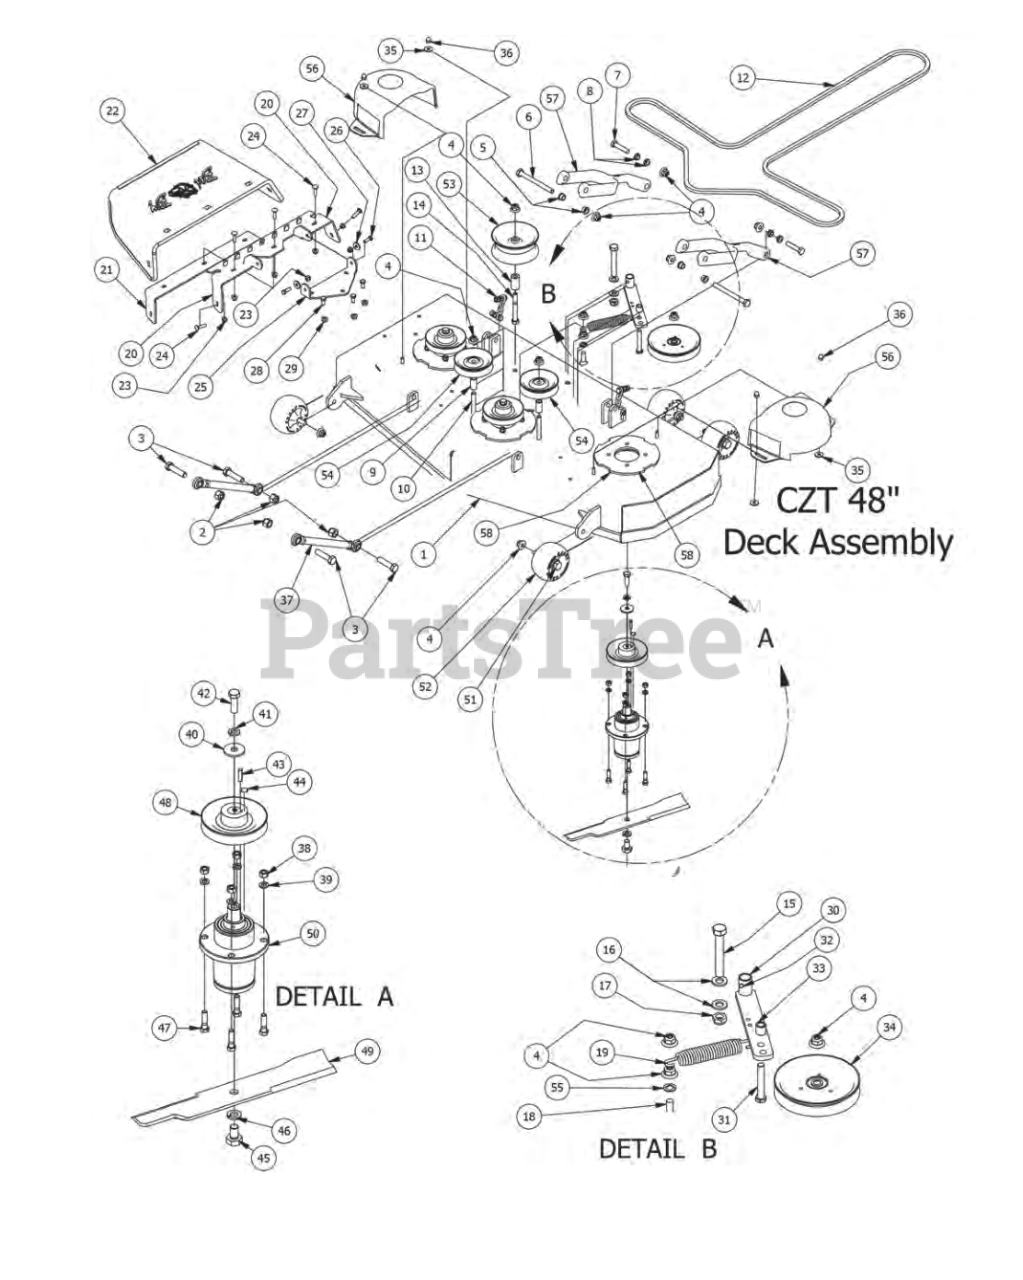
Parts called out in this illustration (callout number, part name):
1	2014 ZT/CZT 48" Deck
2	5/8 Std NC Nylock Nut
3	5/8" x 2 1/2" Gr5 Hex Bolt (Coarse)
4	1/2-13 Nylon Flange Nut-Orange
5	Flange Bushing For Deck Arm upper
6	1/2" x 5 1/2" Bolt
7	1/2-13X 2-1/4 GR Hex Bolts
8	Flange for Lower Deck Arm
9	502 ID X.75 OD X 1.500 Leng
10	1/2 x 3 1/2 Flange Bolt Grade 8
11	2015 CZT Deck Hanger Chain
12	50" Deck Belt
13	1 3/4" Pulley Spacer
14	1/2" x 4" Bolt (Grade 8)
15	5/8" x 4" Hex Bolt
16	635 ID Plastic Washer
17	5/8-11 Nylon Insert Jam Half Nut
18	1/2 x 1-1/2 Carriage Bolt
19	2009 Deck/Pump Idler Spring
20	Upper Hanger
21	Discharge Lower Chute Bracket
22	Rubber Discharge Chute
23	5/16" Nylon Flange Nut
24	5/16" x 1 1/4" Carriage Bolt
25	Discharge Chute Hanger (deck mounted)
26	5/16" x 1" Bolt
27	360 ID Plastic Washer
28	3/8" x 3/4" Hex Bolt
29	3/8" Flange Nut
30	Deck Idler
31	1/2-13 x GR 5 Hex Bolt Zinc
32	1/4" Press in Grease Fitting
33	3/4 OD x 1/2 ID x 314 Length
34	5-3/4 Idler Pulley
35	.360 ID Plastic Washer-Black
36	Acom nut-pulley Cover
37	Turnbuckle (Top Link)
38	3/8" Hex Nut
39	3/8" Lock Washer
40	1/2 Belleville Washer
41	1/2" Lock Washer
42	1/2"-20 x 1 1/2 - Grade 5 Fine Thread Bolt
43	1/4" x 1" Key
44	5/16 Set Screw
45	5/8" x 1 1/2" Gr8 Hex Bolt (Fine)
46	5/8" Lock Washer
47	3/8" x 1 1/2" Hex Bolt
48	5" Deck Pulley
49	48" High Lift Fusion Blade
50	ZT/CZT SPINDLE ASSEMBLY
51	Deck Wheel Bolt
52	Anti-Scalp Rollers
53	53/4" Deck Idler Pulley
54	43/4" Idler Pulley
55	517 Square Hole Round Washer
56	Pulley Cover
57	Deck Arm Assembly
58	Deck Spindle Support Plate 72 inch
